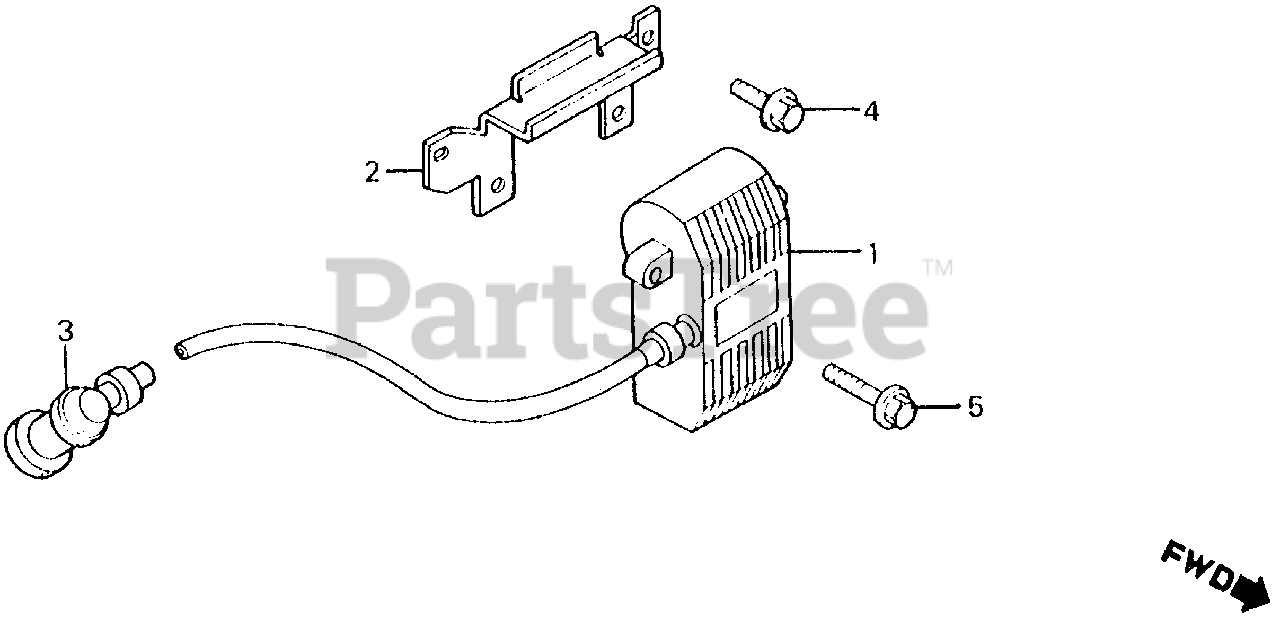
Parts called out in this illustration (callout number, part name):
1	MODULE ASSY., IGNITION CONTROL (CDI) (NOT AVAILABLE)
2	STAY, IGNITION CONTROL MODULE
3	CAP ASSY., NOISE SUPPRESSOR
4	BOLT, FLANGE (6X10)
5	BOLT, FLANGE (6X20)
